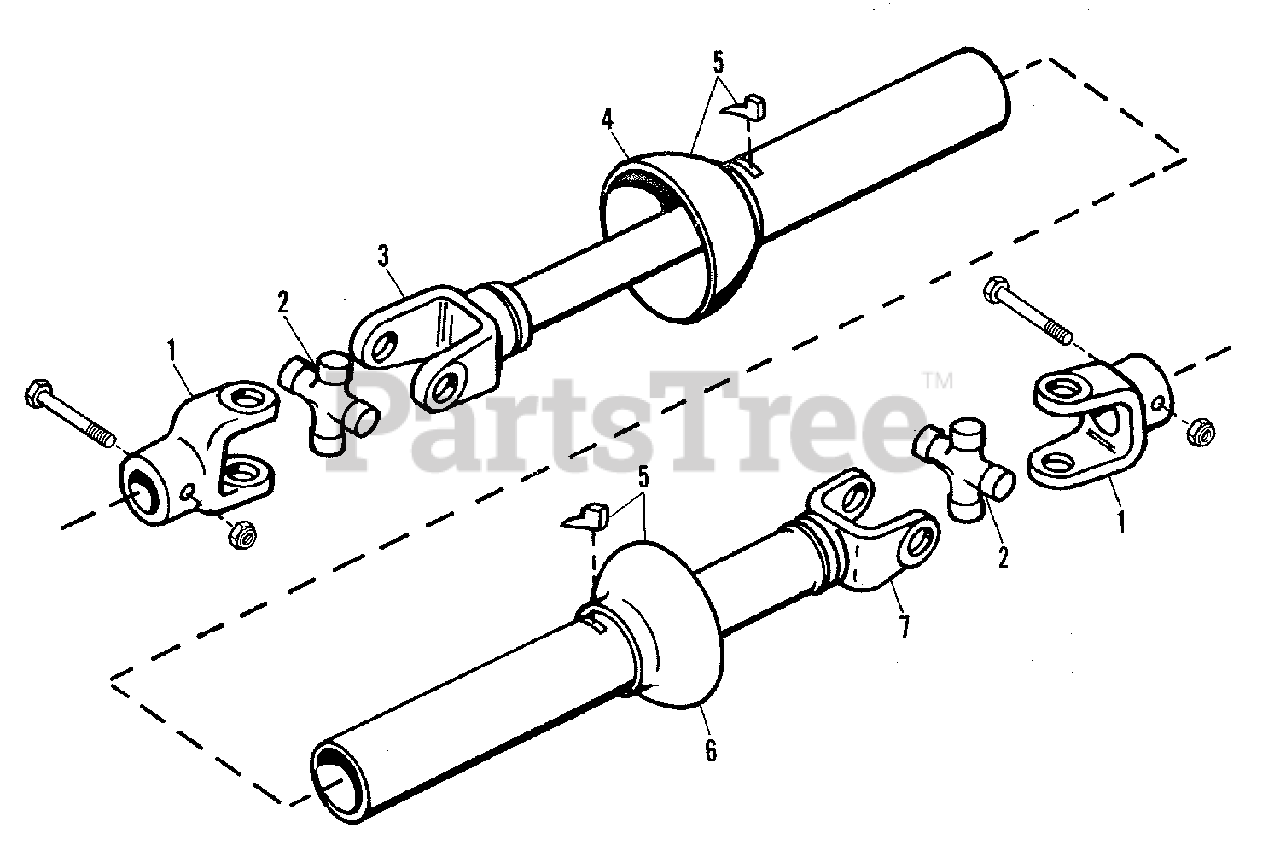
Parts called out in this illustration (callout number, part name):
1	YOKE, End (1" Bore)
1	BOLT, Carriage, 1/4NC x 2-1/2, Gr. 8
1	NUT, Cone Lock, 1/4NC
2	U-JOINT KIT
3	SHAFT & YOKE ASSEMBLY
4	SHIELD, Outer
5	SHIELD ASSEMBLY
6	SHIELD, Inner
7	TUBE & YOKE ASSEMBLY
